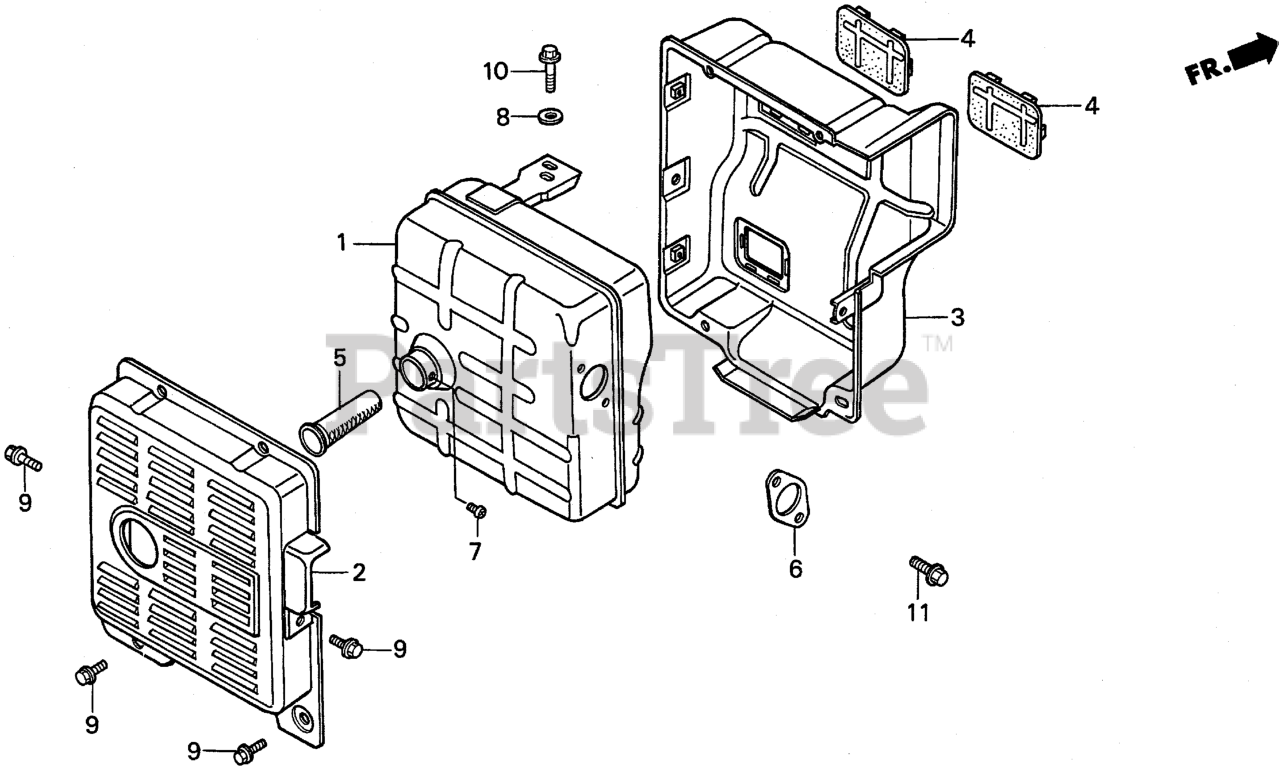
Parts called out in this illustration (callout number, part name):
1	MUFFLER (SANKEI)
2	PROTECTOR, MUFFLER (OUTER)
3	PROTECTOR, MUFFLER (INNER)
4	SEAL, MUFFLER PROTECTOR
5	ARRESTER, SPARK
6	GASKET, EX. PIPE
7	SCREW, TAPPING (4X8)
7	SCREW, TAPPING (4X6) (TO INSTALL OPTIONAL SPARK ARRESTER)
8	WASHER, PLAIN (8MM)
9	BOLT, FLANGE (6X10)
10	BOLT, FLANGE (8X16)
11	BOLT, FLANGE (8X20) Use up to Engine SN 1609606.
